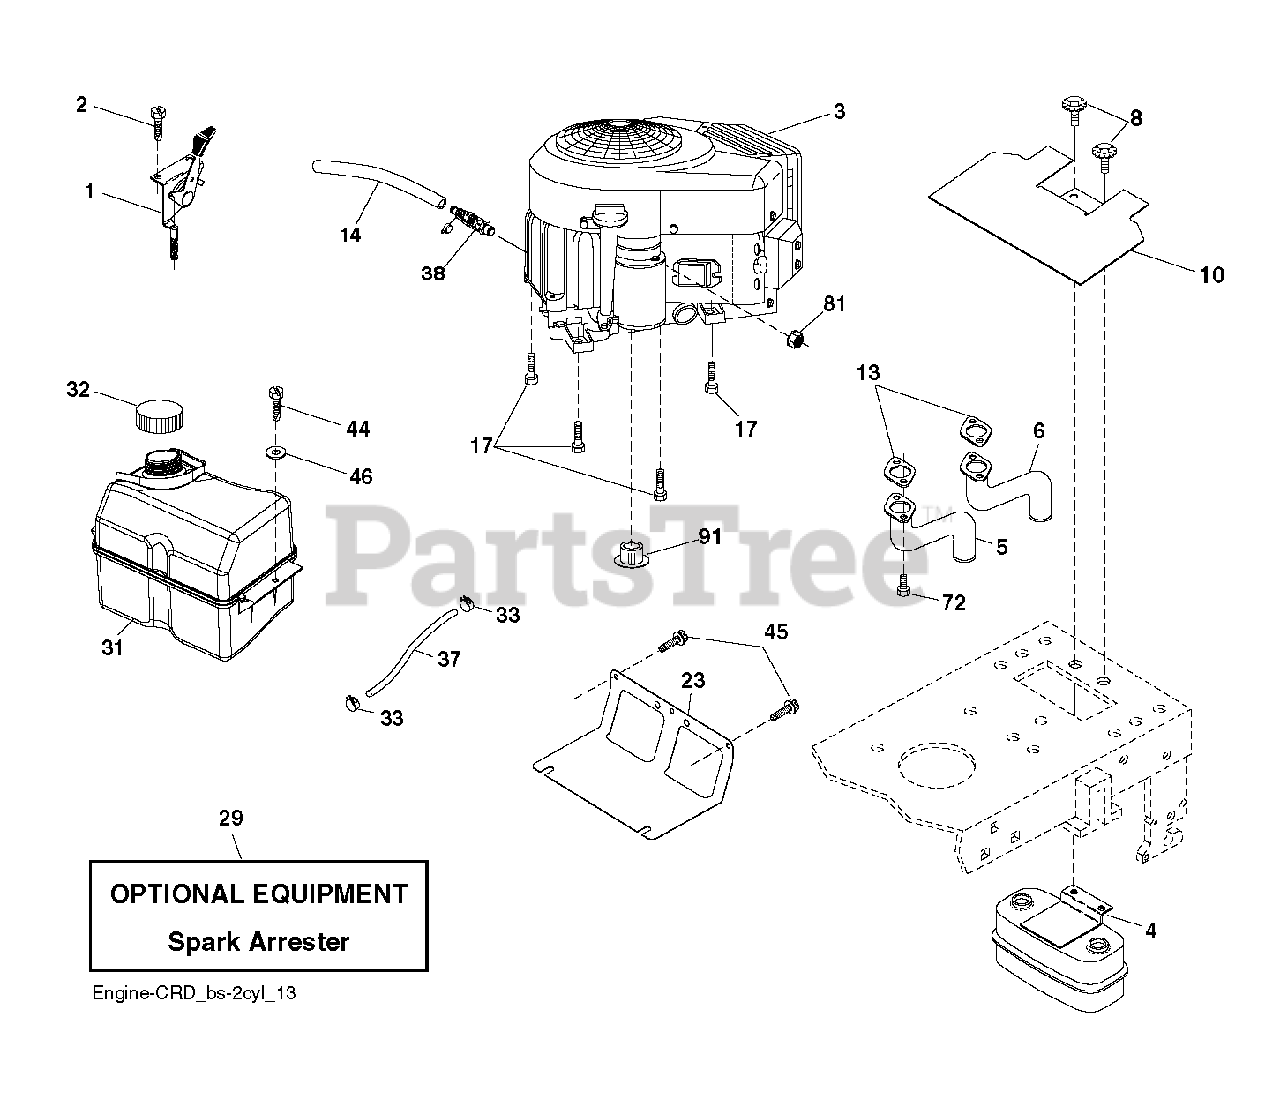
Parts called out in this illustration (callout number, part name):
1	CONTROL.TH/CK.COBRA.B&S.TWN.
2	SCREW.#10 X 0.750.BOS THREAD
4	MUFFLER.TWIN.CYL.LOW.TONE
5	EXHAUST TUBE RH
6	TUBE MANIFOLD LH
8	BOLT, 5/16-18 X 1 3/4
10	SHIELD.HEAT.MUFFLER
13	GASKET.MUFFLER
14	TUBE, DRAIN OIL ASM.
17	SCREW.3/8-16
23	SHEILD.BROWNING.DBR.GUARD
29	ARRESTER SPARK (OPTIONAL)
32	CAP ASM.FUEL.2.25"FR.
33	HOSE CLAMP
37	LINE.FUEL.20
38	VALUE.OIL.DRAIN
44	SCREW HEXWSHR 1/4-20X3/4
45	SCREW, 3/8-16X3/4
72	SCREW.SOCKET.HEAD.5/16-18
81	NUT
91	BUSHING.1.375OD
